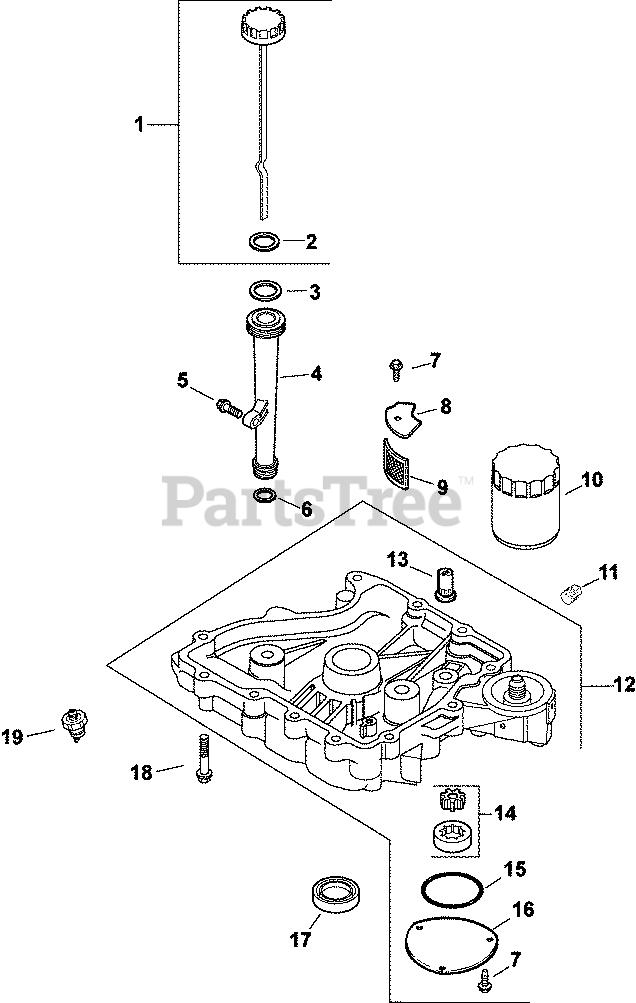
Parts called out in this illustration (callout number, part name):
1	DIPSTICK/CAP ASSY (BLACK)
2	O-RING, DIPSTICK
3	O-RING, UPPER OIL FILL TUBE
4	TUBE, OIL FILL USE 25 123 07-S
5	SCREW, FLG THD FRM M5X.8X20-(#25086399S)
6	O-RING, LOWER OIL FILL TUBE
7	SCREW,FLG THD FRM M5X0.8X16-(#25086398S)
9	SCREEN, OIL-USE 24 162 26-S
10	OIL FILTER
11	PLUG, SQ HD PIPE 3/8"
12	PAN, OIL
13	VALVE, OIL PRESSURE RELIEF
14	PUMP ASSEMBLY, OIL - DISCONTINUED
15	O-RING (2.5" DIA)
16	COVER, OIL PUMP
17	SEAL, OIL
18	SCREW, FLG M8X1.25X45
19	SENSOR, OIL PSI
